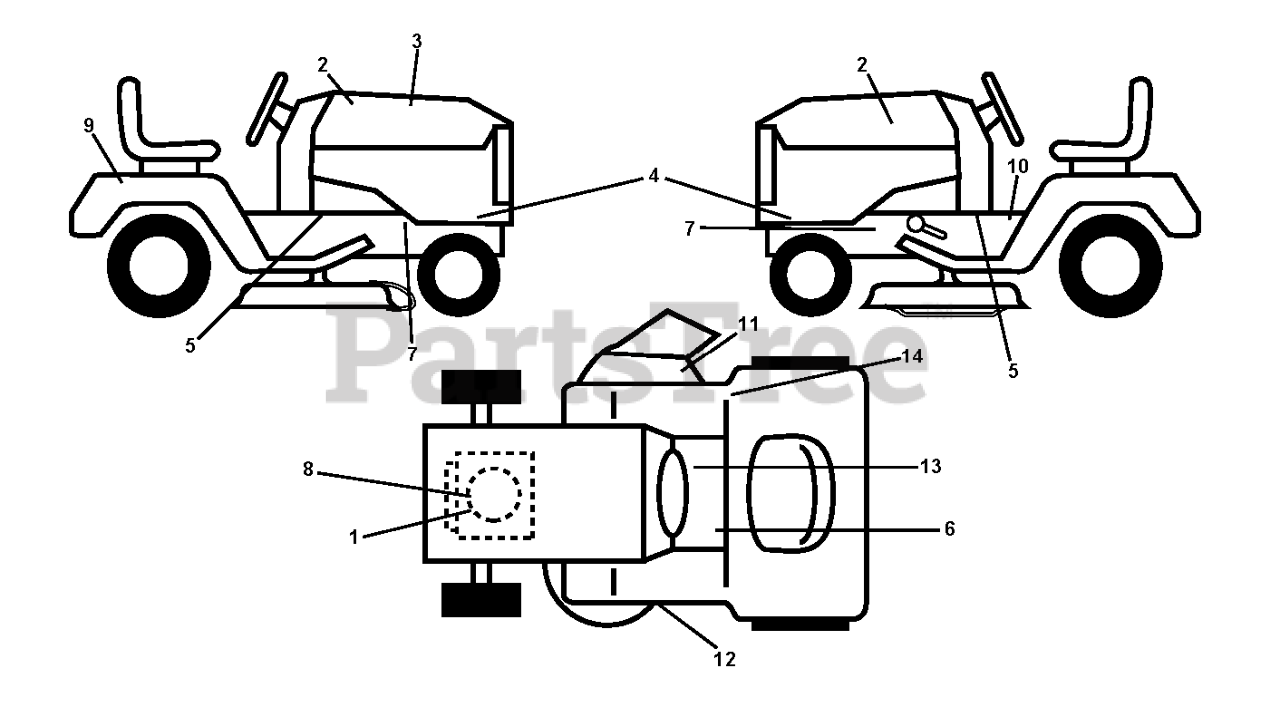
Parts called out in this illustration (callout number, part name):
1	DECAL
2	RP.DECAL.BADGE.170MM.TEXTLOGO
3	Decal, Rpl
6	DECAL
8	Decal, BS Engine
9	DECAL BTRY SYMBOLS
10	LABEL
11	DECAL.WARN.DFLECT/CTFINGR.SRD
12	Decal, Mower V-Belt Schematic
13	DECAL PARK BRAKE
14	Decal, Fender 100 DB/CE
